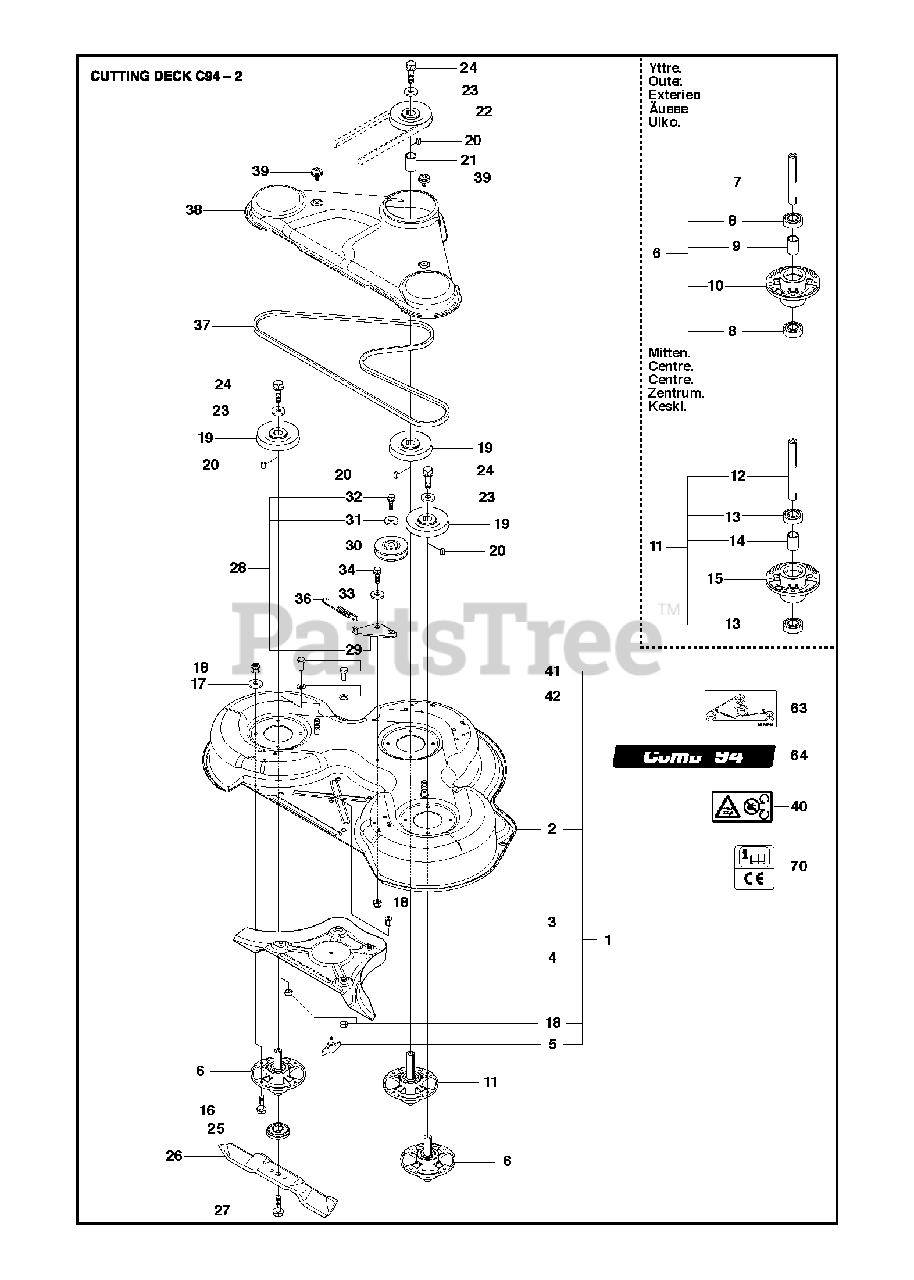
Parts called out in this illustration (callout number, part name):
3	NUT
4	PLUG C93 & C94
5	KNOB
6	BLADE HOUSING ASSY
7	SHAFT
8	BEARING
9	SPACING SLEEVE
10	BEARING HOUSING
13	BEARING
14	SPACING SLEEVE
15	BEARING HOUSING
17	WASHER BRB 8.4X17
18	LOCKNUT M8
21	SPACING SLEEVE
25	BLADE BRACKET
29	BRACKET
30	PULLEY
31	SPACER
32	BOLT
33	WASHER
41	Screw
42	WASHER BRB 8.4X17
